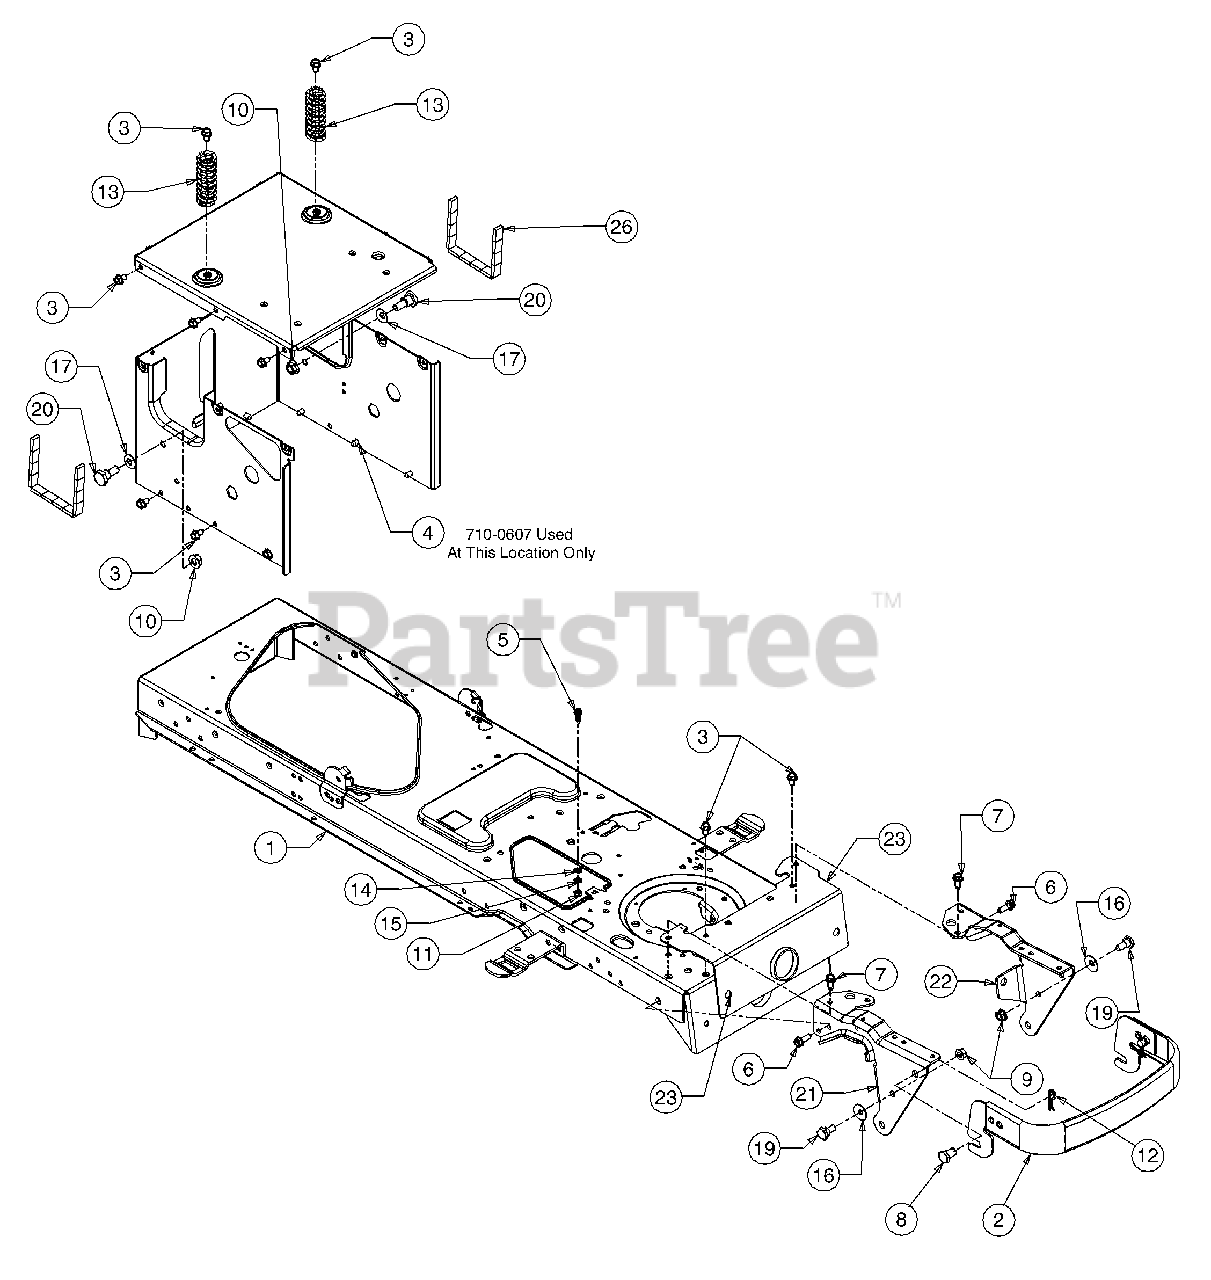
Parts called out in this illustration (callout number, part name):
4	Screw, Self-tapping, 5/16-18, 0.500
5	Screw, Self-tapping, 1/4-20, 0.750
6	Screw, 5/16-18, .875, Gr5
7	Screw, 5/16-18, 0.750
8	Pin, Clevis, .50 Dia x .78 Lg
9	Nut, Flange Lock, 3/8-16
10	Nut, Flange Lock, 7/16-20
11	Nut, Hex, 1/4-20, Gr5
12	Pin, Click, .092 x 1.64 Lg
13	Spring, Compression, 1.28 OD x 3.50 Lg
14	Washer, Lock, Ext 1/4
15	Washer, Lock, 1/4, Regular Duty
16	Washer, Bell, .390 x 1.13 x .062
17	Washer, Bell .45 x 1.00 x .062
19	Shoulder Screw, 3/8-16
20	Shoulder Screw .625 x .500, 7/16-20
